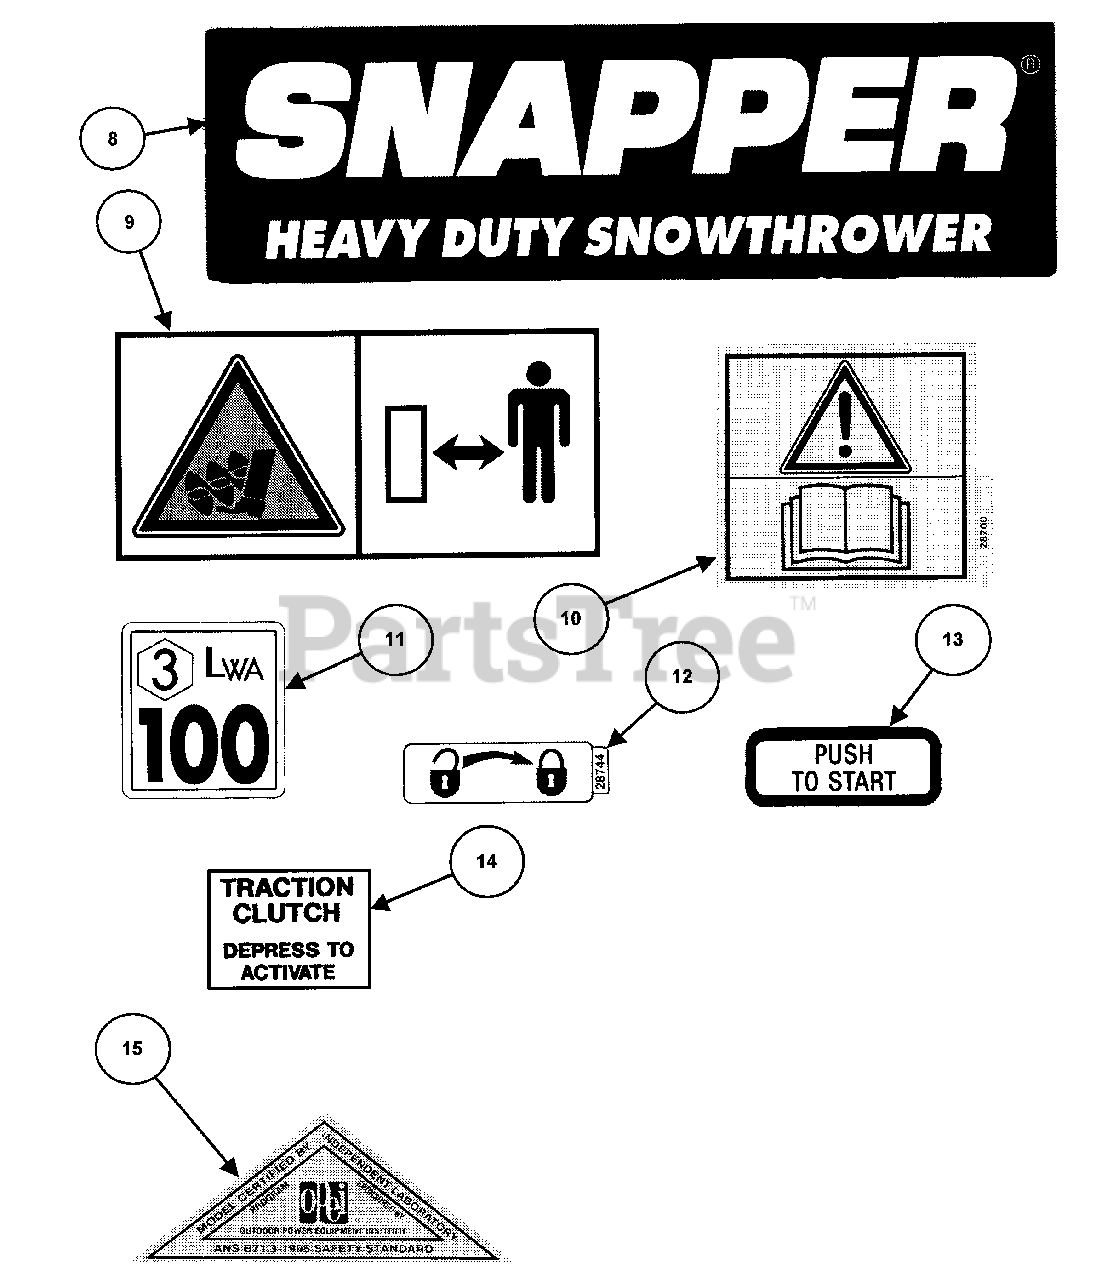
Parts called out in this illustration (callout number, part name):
8	DECAL, Heavy Duty Snow
9	DECAL, Foot Danger (Euro)
10	DECAL, Chute/Read Manual (Euro)
11	DECAL, Noise
12	DECAL, Turn To Lock
13	DECAL, Start
14	DECAL, Traction Clutch
15	DECAL, OPEI Snow
